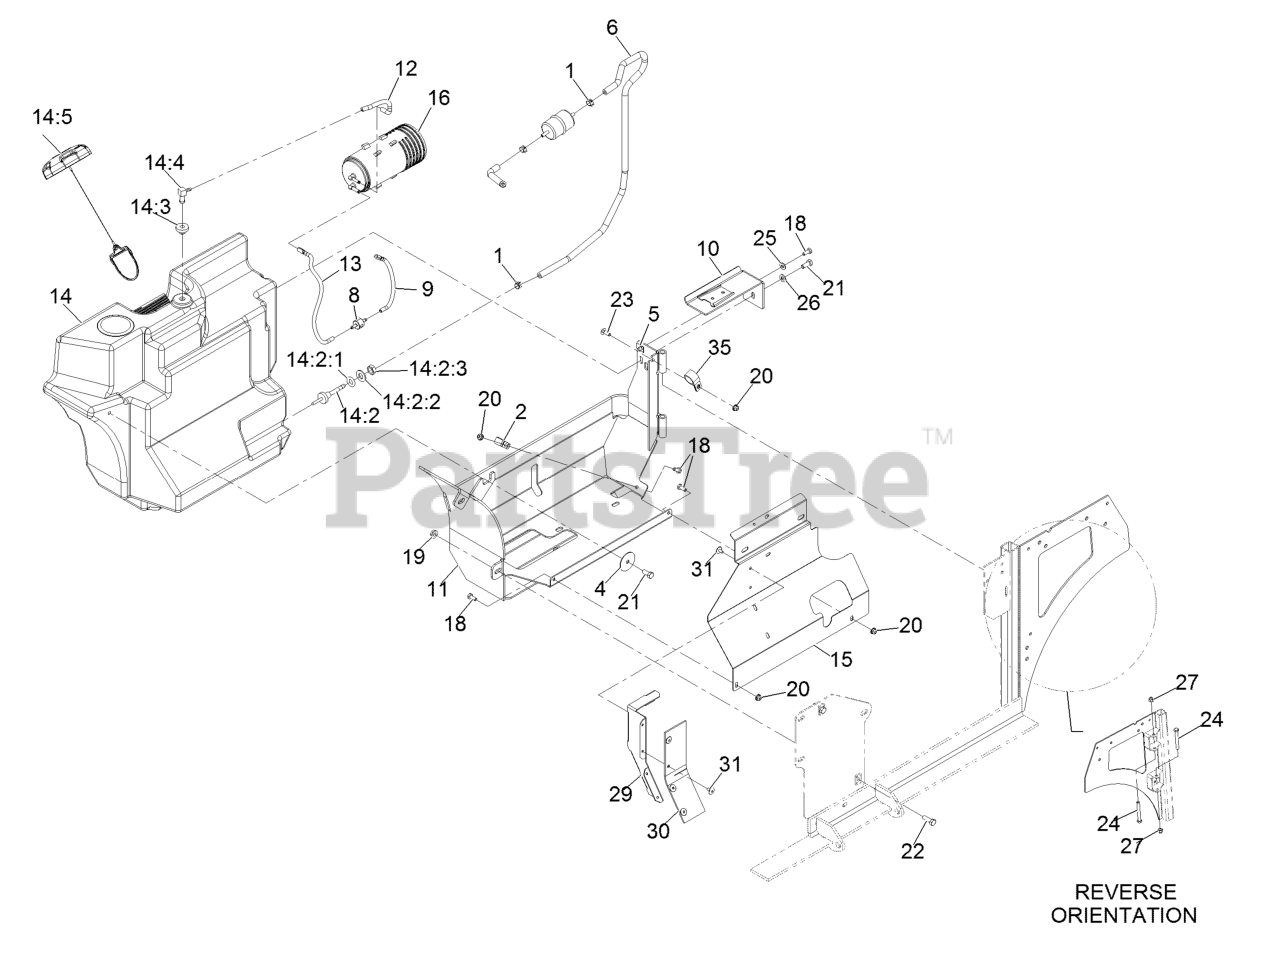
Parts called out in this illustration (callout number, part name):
1	Clamp-Hose
2	Clip-Loom 1/2
5	Nut-Retainer-Panel 1/4-20
6	Hose-Fuel Line 29"
8	Valve-Check, Vacuum
9	Hose-Vent, Formed
10	Canister Bracket ASM
11	Tank Frame ASM
12	Hose-Vent, Formed
13	Hose-Vent, Formed
14	Fuel Tank ASM
14:2	Fitting-Fuel Bulkhead W/Screen
14:2:2	Washer-1/2 SAE
14:2:3	Nut-Jam 1/2-20
14:3	Bushing
14:4	Fitting-90 DEG
14:5	Cap-Fuel, Ratcheting
15	Panel-Tank Shield
16	Canister-Carbon, 800Cc
18	Screw-HH 1/4-20 X 5/8
19	Nut-Whizlock 5/16-18
20	Nut-Nyloc 1/4-20 Flg
21	Screw-HH 5/16-18 X 3/4
22	Screw-HH 5/16-18 X 1
23	Bolt-Carriage 1/4-20 X 3/4
24	Screw-HH 3/8-16 X 3
25	Washer-1/4 SAE
26	Washer-5/16 SAE
27	Nut-Nyloc 3/8-16
29	Deflector-Air
30	Flap-Rubber
31	Rivet 3/16 X 1/4
35	R-Clamp
